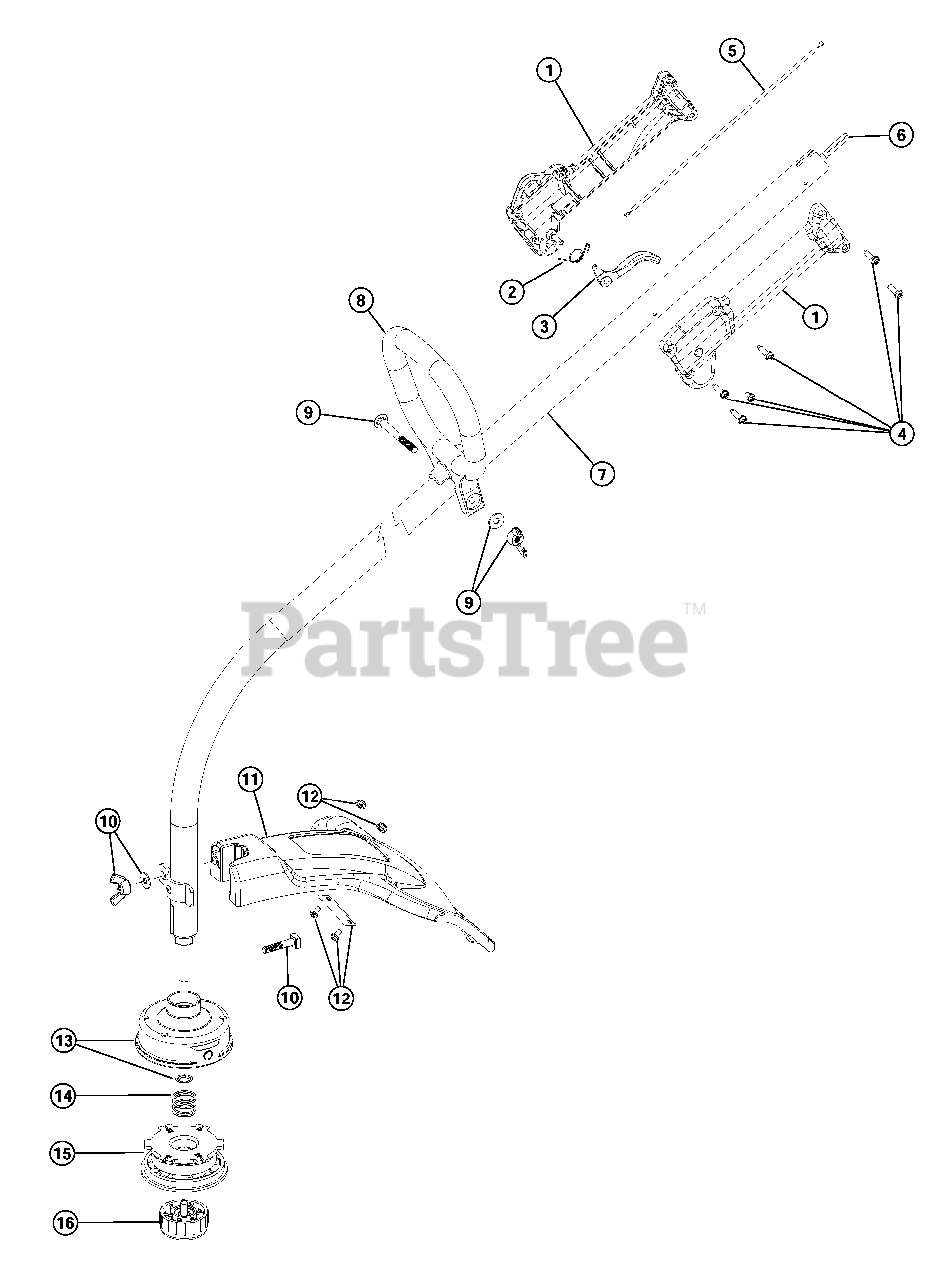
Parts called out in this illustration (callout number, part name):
1	Throttle Housing and Trigger Assembly
2	Throttle Trigger Spring
3	Throttle Trigger
4	Throttle Housing Screws
5	Throttle Cable
6	Flexible Drive Shaft
7	Drive Shaft Housing Assembly
8	D-Handle Assembly
9	D-Handle Hardware
10	Guard Mounting Hardware
12	Blade Assembly
13	Outer Reel w/Retainer
14	Spring
15	Inner Reel
16	Bump Knob
